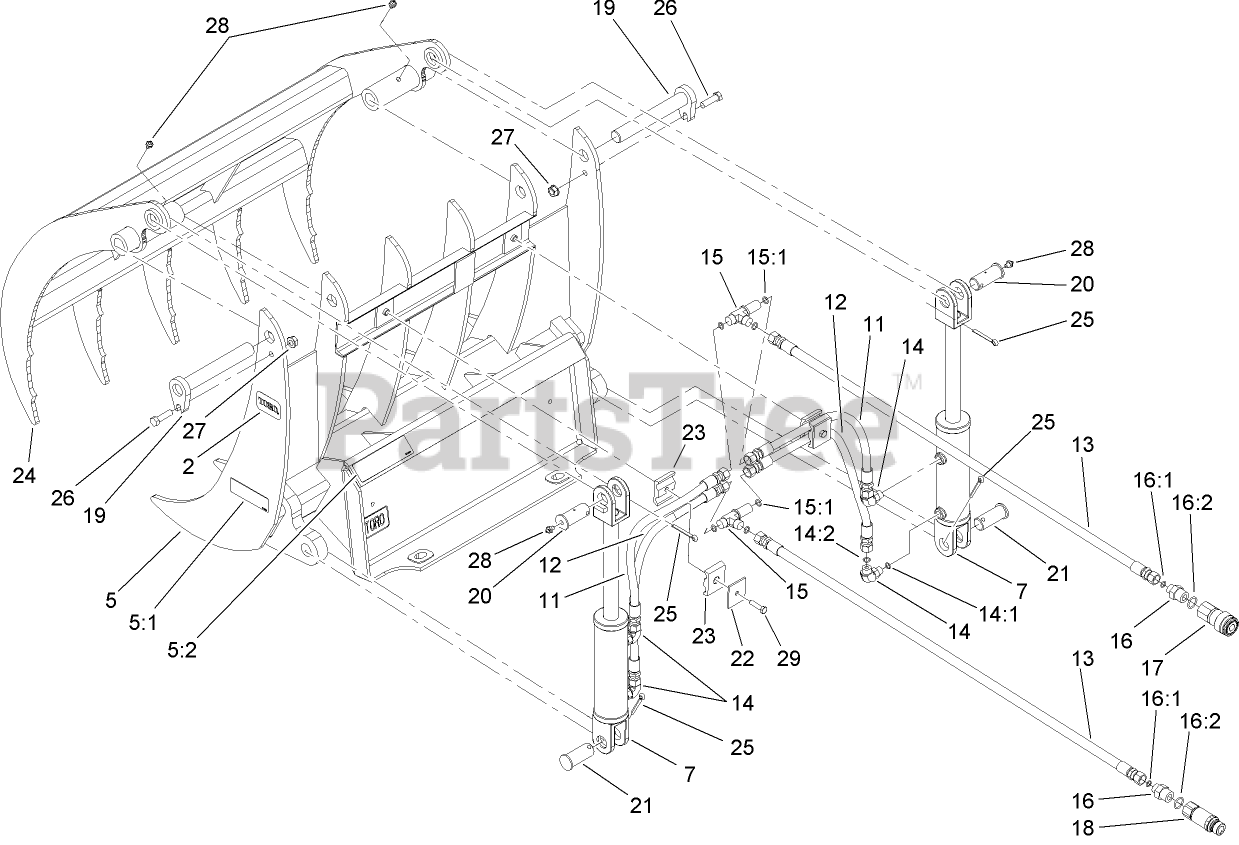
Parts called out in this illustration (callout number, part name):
2	Decal
5	BOTTOM GRAPPLE RAKE ASM
5:1	DECAL-WARNING
5:2	DECAL-CAPACITY
7	CYLINDER-HYD
11	HOSE ASM-HYD
12	HOSE ASM-HYD
13	HOSE ASM-HYD
14	FITTING-ELBOW, 90 DEG
14:1	O-RING
14:2	O-RING
15	FITTING-TEE, BULKHEAD
15:1	O-RING
16	FITTING-HYD, STRAIGHT
16:1	O-RING
16:2	O-RING
17	COUPLER-FACE, FLUSH
18	NIPPLE-CONNECT, PRESSURE
19	PIN-FLAG
20	PIN-CYLINDER, GREASEABLE
21	PIN-CYLINDER
22	GUIDE-HOSE, PLATE
23	GUIDE-HOSE, HALF
24	TINES-GRAPPLE, TOP
25	PIN-COTTER
26	SCREW-HH
27	NUT-HF
28	FITTING-GREASE
29	SCREW-HH
